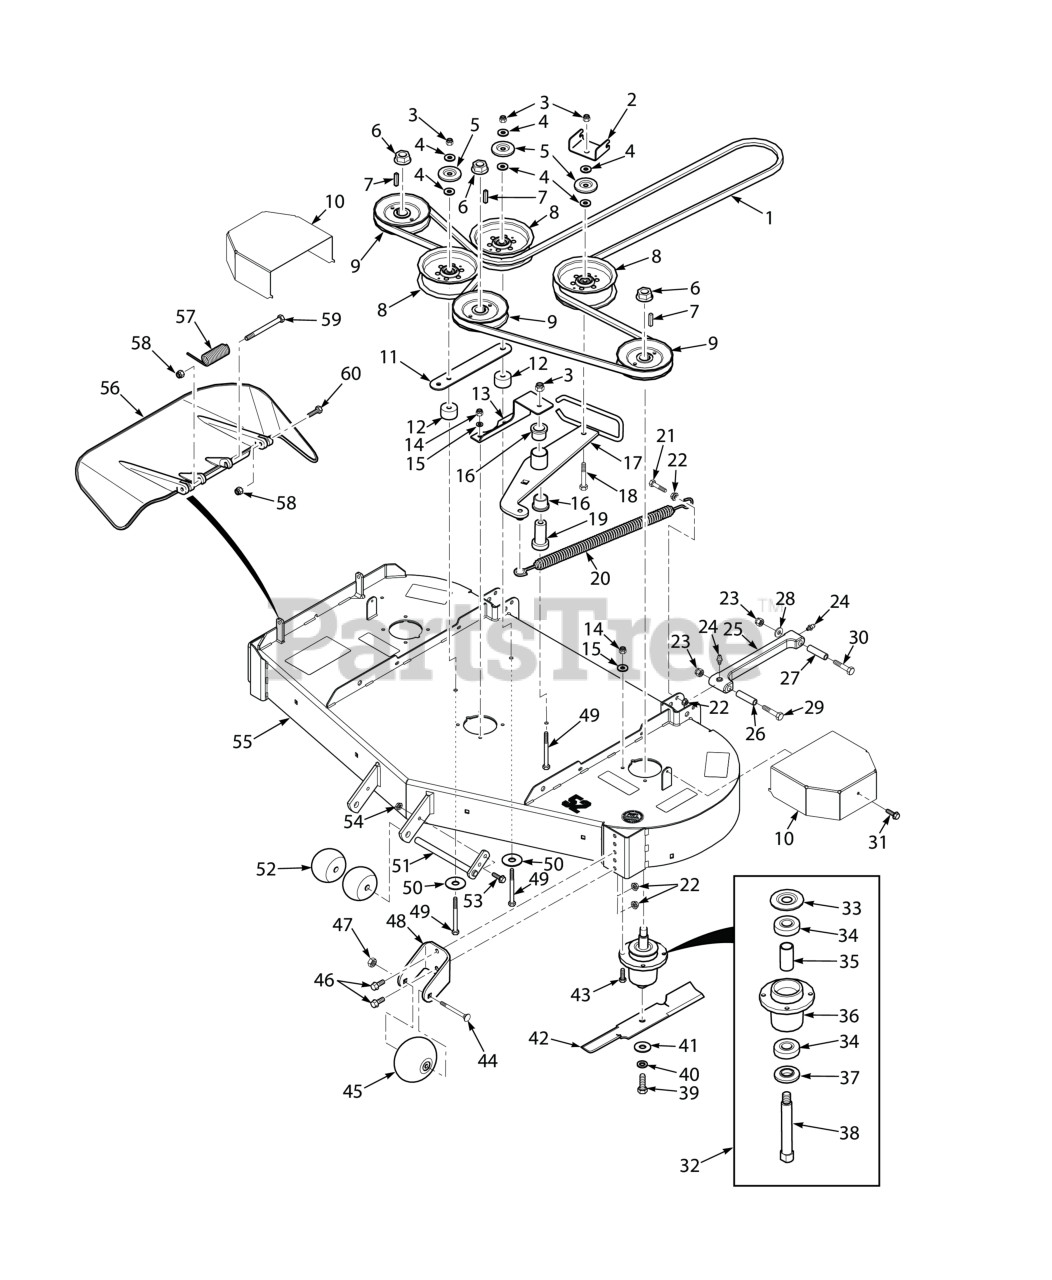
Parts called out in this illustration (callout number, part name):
1	Belt, Cutter Deck -48
2	Bracket, Belt Guide
3	HEX NUT, ELASTIC STOP LOCK, 3/8-16
4	Flatwasher, 3/8 (.391 x .938 x .105 HD) Grade 8
5	Quick Pin, 5/16" Dia.
6	Nut, 3/4-16 Spriral Lock
7	Key, 1/4 x 1/4 x 1.25" Pulley Mtg.
8	Pulley, 5" Idler
9	Pulley, 5.13" OD - 25mm Bore
10	Belt Cover, SZL
11	Brace, Pulley
12	Spacer, Idler Pulley
13	Support, Idler Pivot - 48
14	Lock Nut, 5/16-18 Elastic Stop Grade 8
15	Lockwasher, 5/16 (.317 x .586 x .078) Helical Spring
16	Bearing, Plastic
17	Idler Arm (incl. item #15)
18	Capscrew, Hex Head 3/8-16 x 2-1/2"
19	Pivot, Idler
20	Spring, Cutter Deck Idler
21	Bolt, Hex Head 3/8-16 x 1-1/2" Grade 8 Black
22	NUT, 3/8-16 SERRATED FLANGE HEX HEAD
23	HEX LOCKNUT, ELASTIC STOP, 1/2-13
24	GREASE FITTING, STR. 1/4-28 SELF TAP.
25	Pusharm Assembly, LH
26	Spacer, Pusharm - Deck
27	Spacer, Pusharm - Axle
28	Flatwasher, 1/2 - .531 x 1.062 x .095
29	Bolt, Hex Head 1/2-13 x 3-1/2"
30	Bolt, Hex Hd. 1/2-13 x 2-1/2" (lower)
31	Screw, 1/4-20 x .375"
32	Spindle Assembly
33	Debris Shield
34	Bearing
35	Spacer, Bearing
36	Spindle Housing Assembly
37	Protector, Bearing
38	Shaft, Spindle
39	Bolt, Hex Head 5/8-11 x 1-1/2"
40	Lockwasher, 5/8" Spring
41	Flatwasher, 5/8-.688 x 1-3/4 x .134 HD
42	Cutter Blade, 16-1/2" (48V)
43	Bolt, Hex Head 5/16-18 x 1-1/2" Grade 8
44	Bolt, Hex Head 3/8-16 x 3-1/2"
45	Bolt, Carriage 3/8-16 x 4"
46	Capscrew, 3/8-16 x 1.0" Serrated Flange Hex Hd
47	Bolt, Hex Head 3/8-16 x 1" Ser. Flg.
48	Bracket, Anti-Scalp, (Black)
49	Bolt, Hex Head, 3/8-16 x 3-1/2"
50	Flatwasher, 3/8-.406 x 2.25" x .1875
51	Shaft Weldment, Guide Roller
52	Wheel, Anti-Scalp
53	Bolt, Heax Head 5/16-18 x 1" (48V / 52V)
54	Nut, Flange Head Elastic Stop 5/16-18
55	Cutter Deck w/Decals, SWZT48H
56	Discharge Chute Assy. SFZ48
57	Spring, Discharge Chute
58	HEX NUT, ELASTIC STOP LOCK, 5/16-18
59	Bolt, 5/16-18 x 4-3/4" Hex Head
60	Bolt, Hex Head 5/16-18 x 1-1/2" - Front
